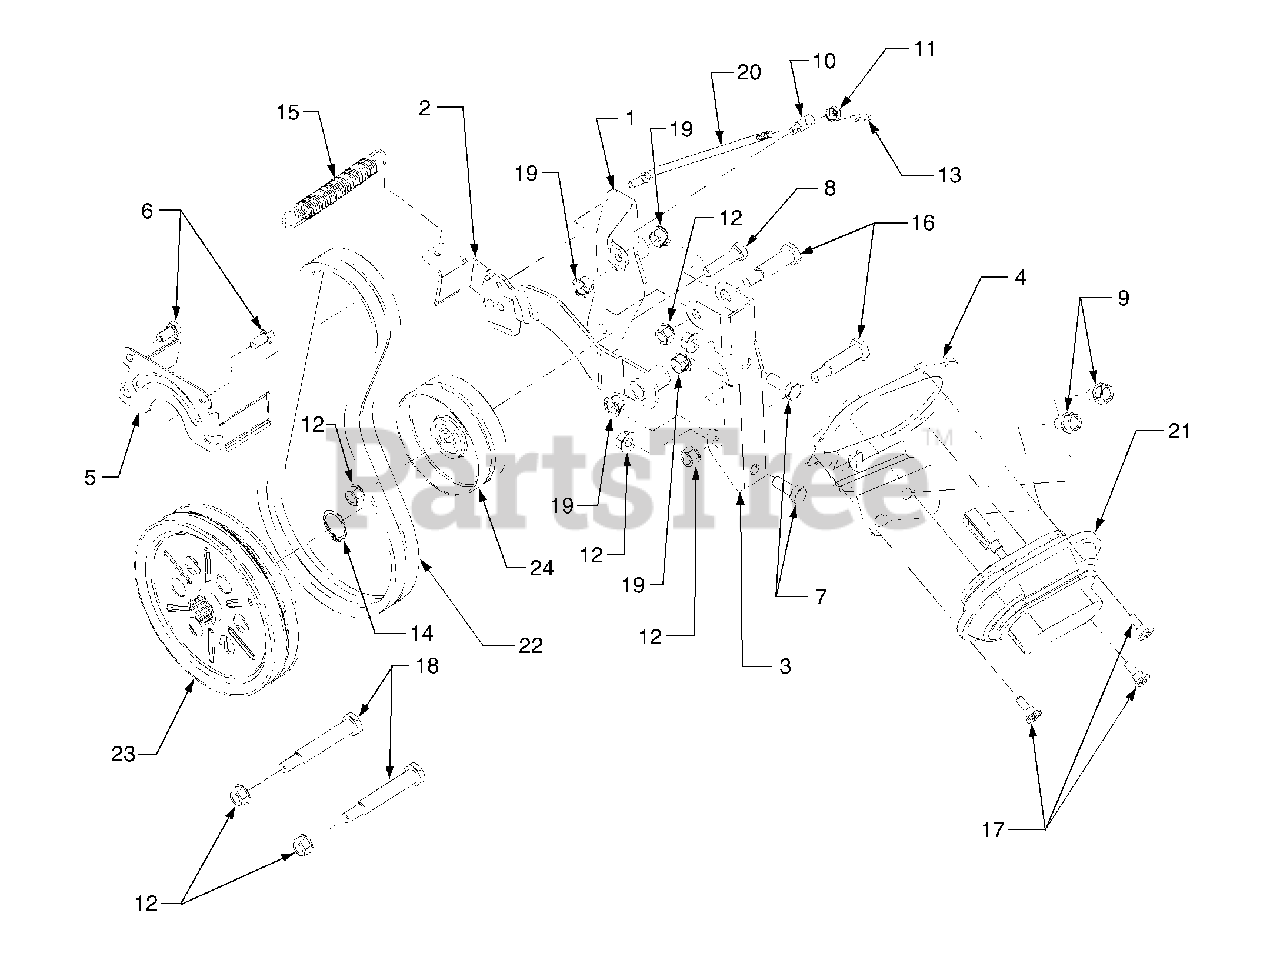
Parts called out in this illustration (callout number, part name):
1	Bracket, Idler
2	Bracket Assembly, Brake
3	Bracket, PTO Mounting
4	Bracket, Actuator
6	Screw, Hex Cap 5/16-24 x .625 GR5
7	Screw, Hex Cap 3/8-16 x 1.0 GR5
8	Screw, Hex Cap 3/8-16 x 1.5 GR5
9	Screw, Hex Wash. Hd. Tapp 3/8-16 x .75
10	Ferrule, Brake Adjustment
11	Nut, Hex Insert Lock, 1/4-20
12	Nut, Flange Lock, 3/8-16
13	Pin, Internal Cotter
14	Snap Ring, 1.0 Dia Shaft
15	Spring, Extension, .530 x 4.74
16	Shoulder Screw, .498 x 1.45
17	Shoulder Screw, .375 x .28
18	Shoulder Screw
19	Bearing, Nylon Flange
20	Rod, PTO Brake
21	Vacuum Actuator
22	V-Belt, A-Section x 37.63
23	Pulley, PTO Drive. 6.75-Double
24	Pulley, Flat Idler, 4.0
